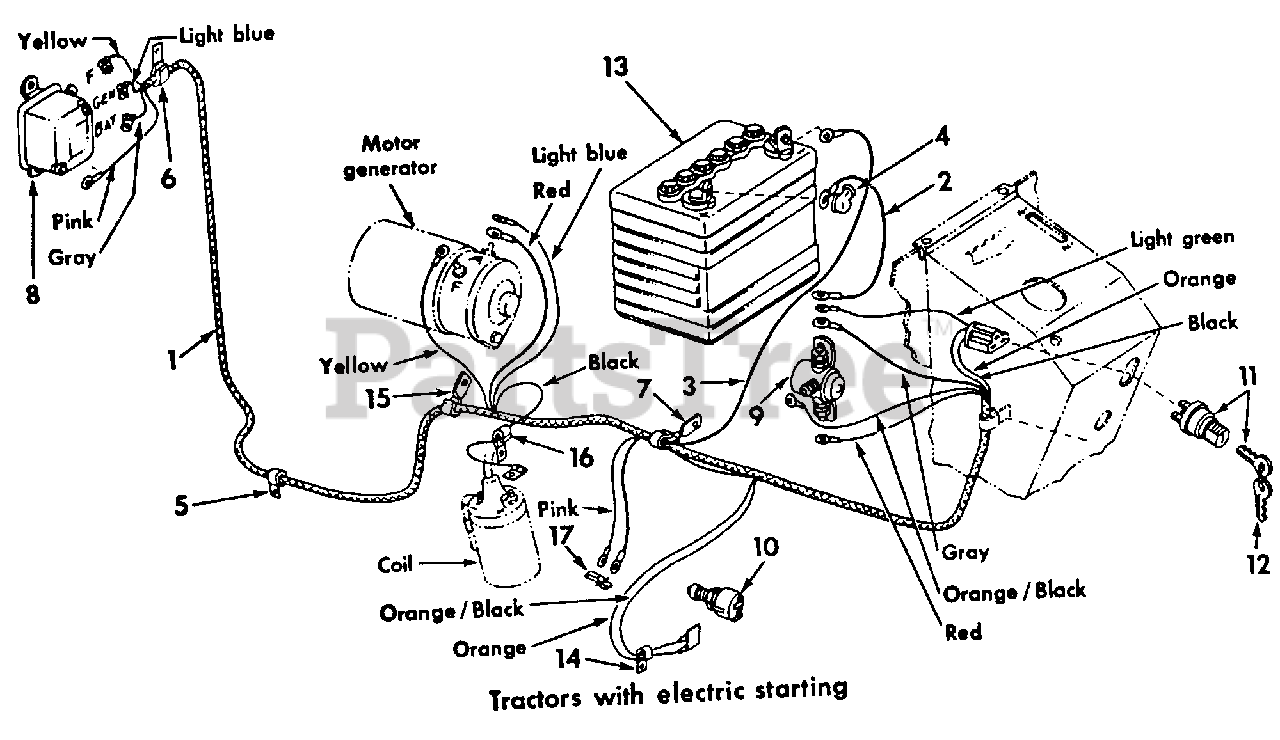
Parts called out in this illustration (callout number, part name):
1	Harness Assy, Cable
2	Cable Assy, Battery to Magnetic Switch
3	Cable Assy, Battery to Ground
4	Cover, Battery Terminal
5	Clip, Cable Harness
6	Clip, Cable Harness
7	Clip, Cable Harness
8	Regulator, Voltage
9	Switch Assy, Magnetic
10	Switch Assy, Safety Starting
11	Switch Assy, Ignition
12	Key, Switch
13	Battery, Prestolite 9948X 12 Volt
14	Clip, Cable
15	Clip, Cable Harness
16	Clip, Cable
17	Clip, Safety Starting Switch Cable Snap On
